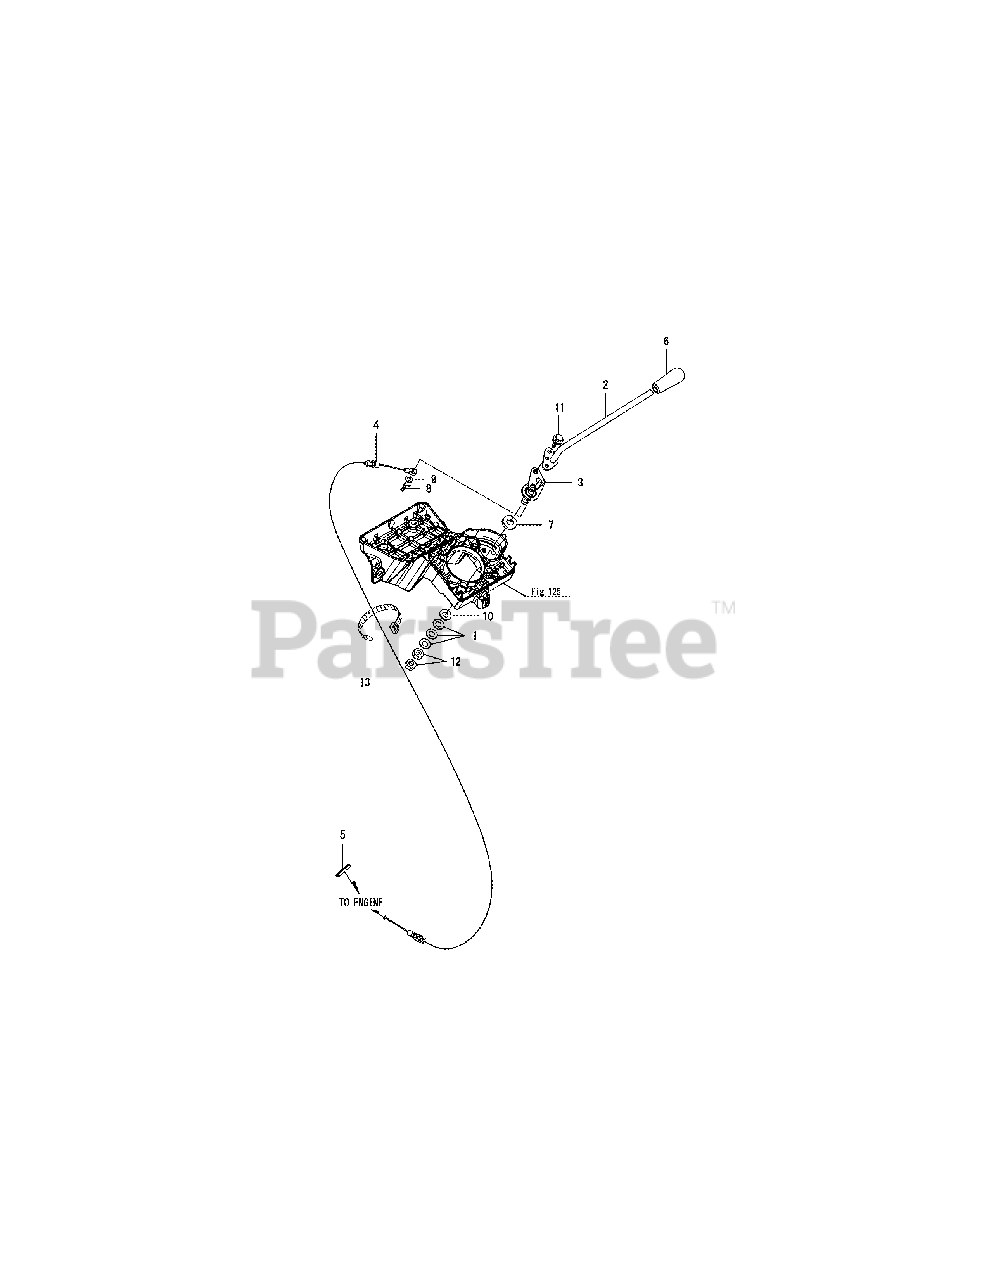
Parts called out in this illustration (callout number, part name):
1	WASHER 10, CONICAL
2	CONTROL LEVER, HEAD
3	CONTROL LEVER, BASE
4	CABLE ASSY, CONTROL
5	RUBBER, WIRE RETAING
6	KNOB, THROTTLE LEVER
7	SPACER 13X26X5
8	PIN 6, COME-OFF SNAP
9	WASHER 6, POLISHED
10	WASHER 10, POLISHED
11	BOLT M 6X 12 PLATED
